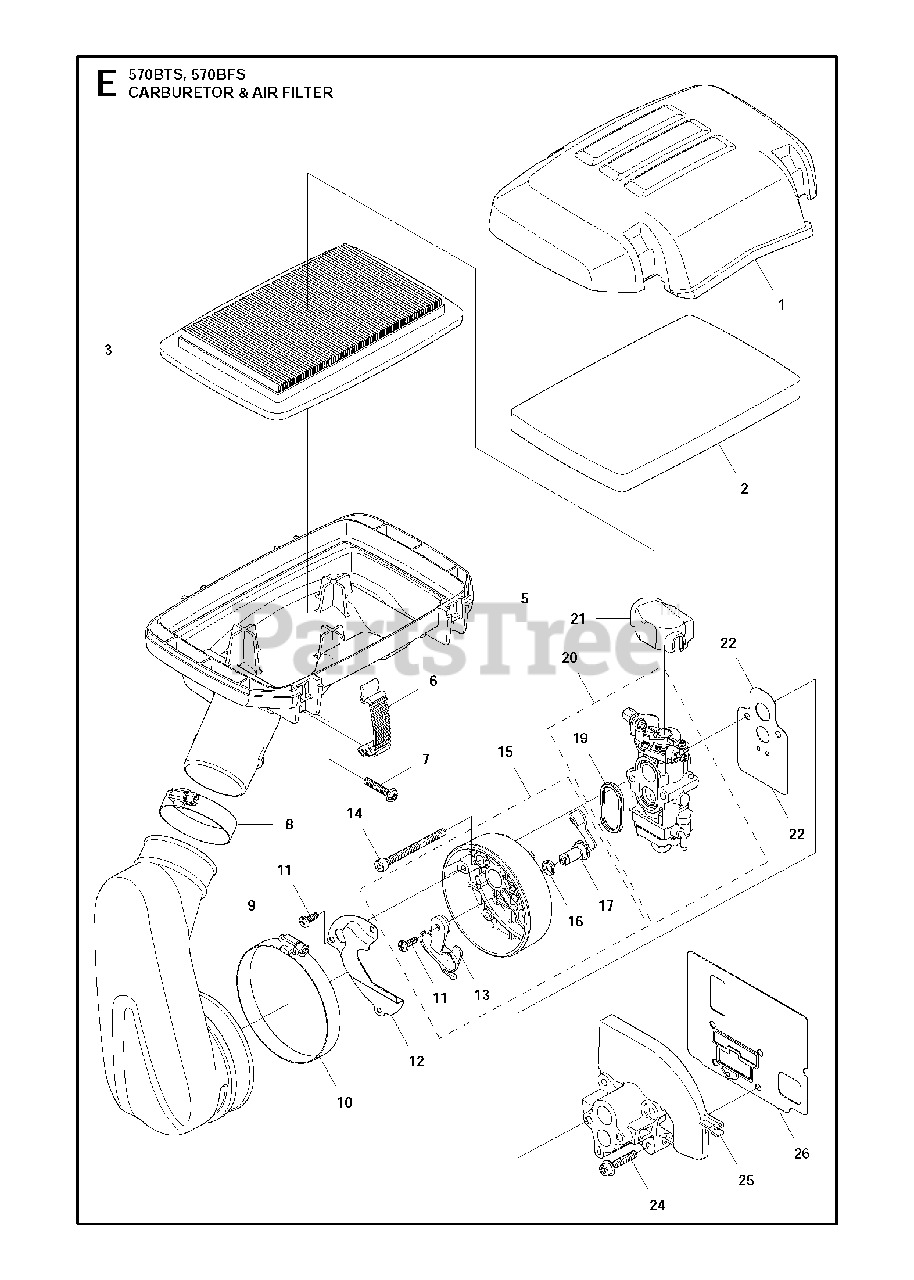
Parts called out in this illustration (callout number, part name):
1	COVER AIR FILTER
2	ELEMENT
3	ELEMENT
5	HOLDER AIR FILTER
6	BUCKLE ORANGE
8	CLAMP(F64)
9	HOSE AIR FILTER
10	CLAMP(F96)
11	SCREW
12	PLATE
13	PLATE CHOKE
16	O-RING
17	LEVER
19	RING
20	CARB
25	INSULATOR
